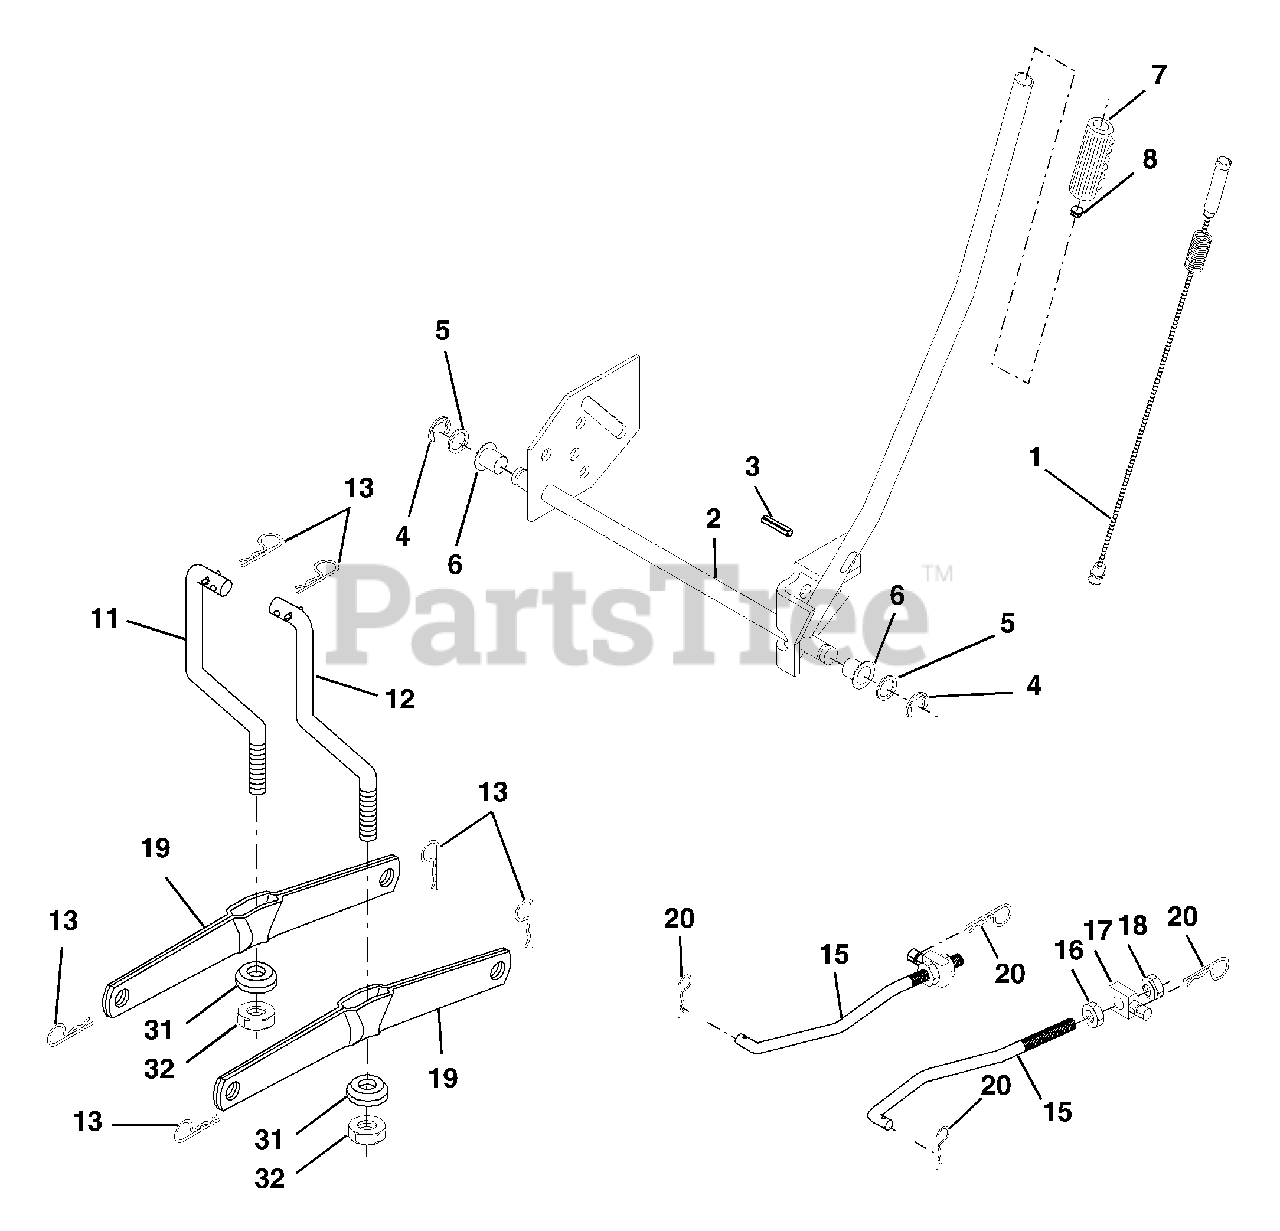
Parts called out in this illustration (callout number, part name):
1	Wire Asm Inner/Sprg w/Plunger
2	Shaft Asm Lift
3	Pin Groove
4	E Ring #5133-62
5	Washer 21/32 x 1 x 21 Ga.
6	Bearing Nylon
7	Grip Handle
8	Button Plunger
11	Link Lift Lh
12	Link Lift Rh
13	Retainer Spring
15	Link Front
16	Nut Jam Hex 1/2-13 Unc
17	Trunnion Blk Zinc
18	Nut Lock W/Wsh 1/2-13 Unc
19	Arm Suspension Rear
20	Retainer Spring
31	Bearing Pvt Lift Spherical
32	Nut Crownlock 3/8-24
